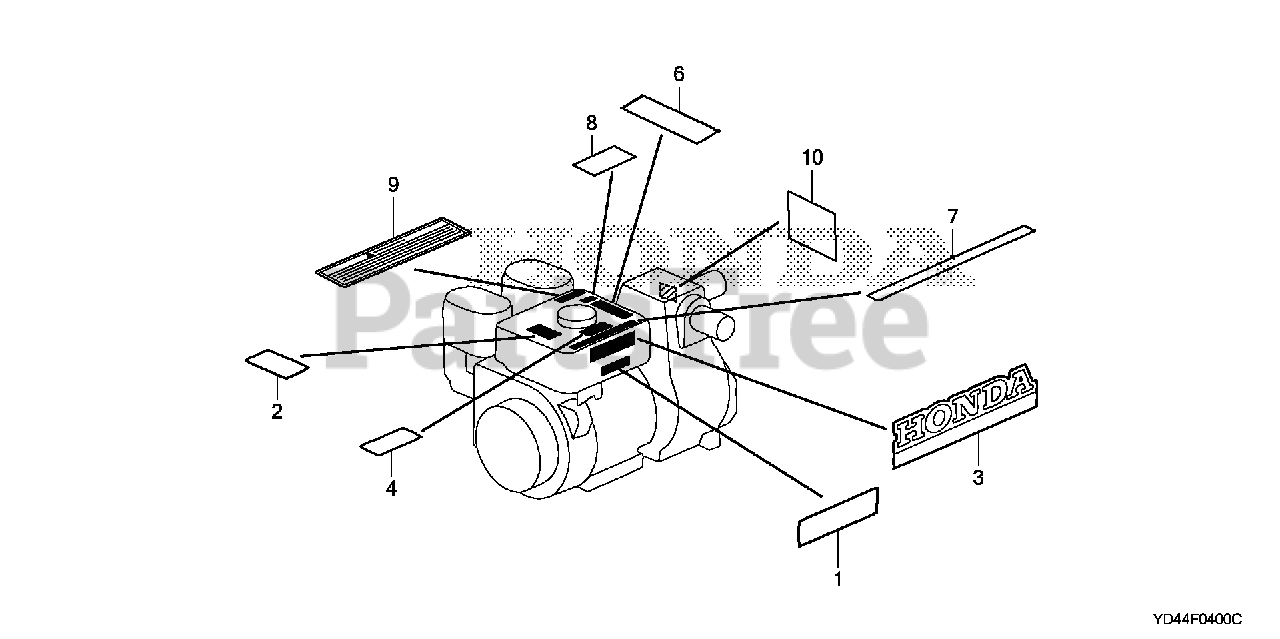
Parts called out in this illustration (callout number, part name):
1	MARK, CAUTION (PUMP)
2	LABEL, PUMP WARNING
3	MARK (WT40X)
